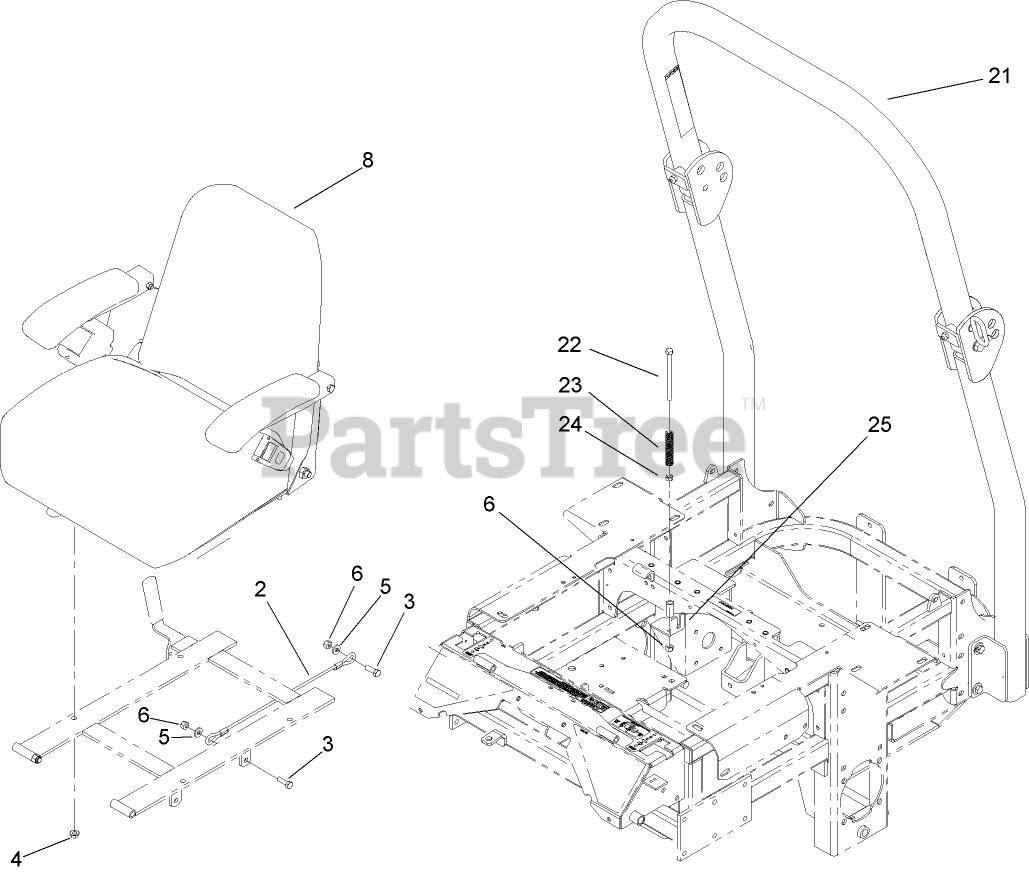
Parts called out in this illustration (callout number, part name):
2	CABLE-SEAT
3	SCREW-HH
4	NUT-HF
5	WASHER
6	NUT-LOCK, NI
8	SEAT ASM
21	ROPS KIT
22	SCREW-HH
23	SPRING-SWITCH, SEAT
24	NUT-HEX
25	PLATE-SWITCH, SEAT
